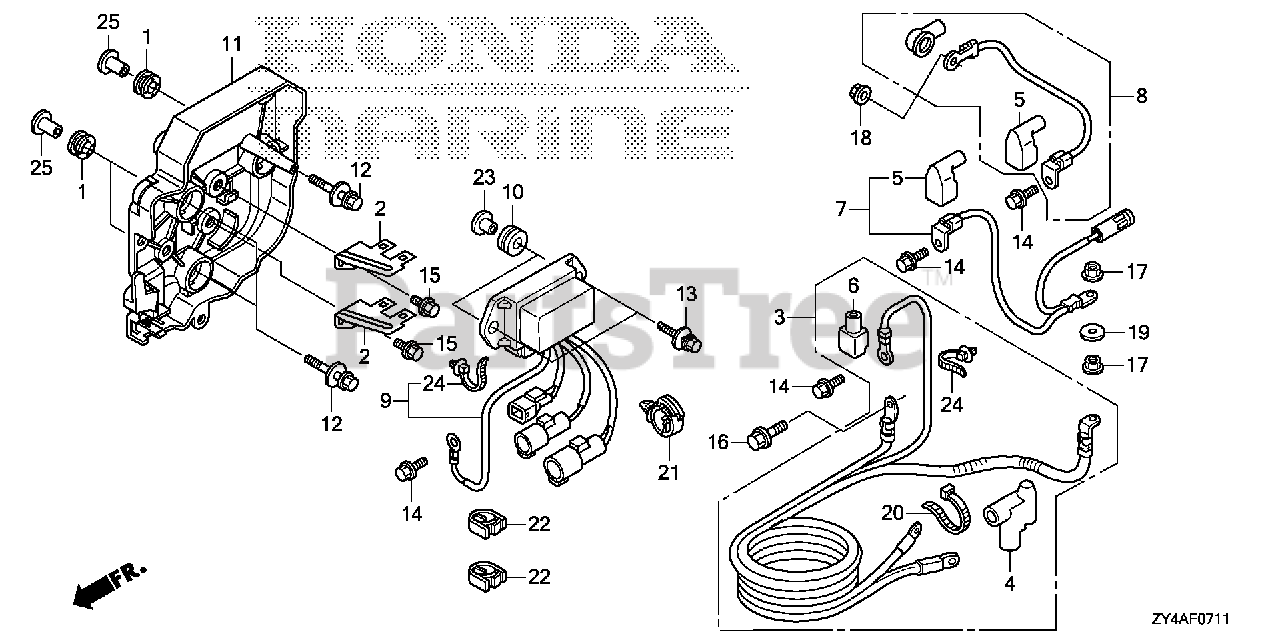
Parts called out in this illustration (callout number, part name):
1	GROMMET, ELECTRONIC PARTS CASE
2	BRACKET C, CONNECTOR
3	CABLE ASSY., STARTER
4	COVER, STARTER TERMINAL
5	COVER B, TERMINAL (L)
6	COVER B, TERMINAL
7	CABLE ASSY., POWER TILT RELAY
8	WIRE, ALTERNATOR
9	RELAY ASSY., POWER TILT
10	GROMMET, RELAY
11	CASE, POWER TILT RELAY
12	BOLT-WASHER (6X27) (CT200)
12	BOLT-WASHER (6X27)
13	BOLT-WASHER (6X25)
14	BOLT, FLANGE (6X12)
15	BOLT, FLANGE (6X10)
16	BOLT, FLANGE (8X18)
17	NUT-WASHER (8MM)
18	NUT-WASHER (6MM)
19	WASHER, PLAIN (8MM)
20	BAND, WIRE (165MM) (BLACK)
21	CLIP, WIRE HARNESS
22	CLIP, WIRE HARNESS
23	COLLAR, MOUNTING (6MM)
24	CLIP, HARNESS BAND (145MM) (BLACK)
25	COLLAR, MODULE IGNITION CONTROL CASE (CDI)
